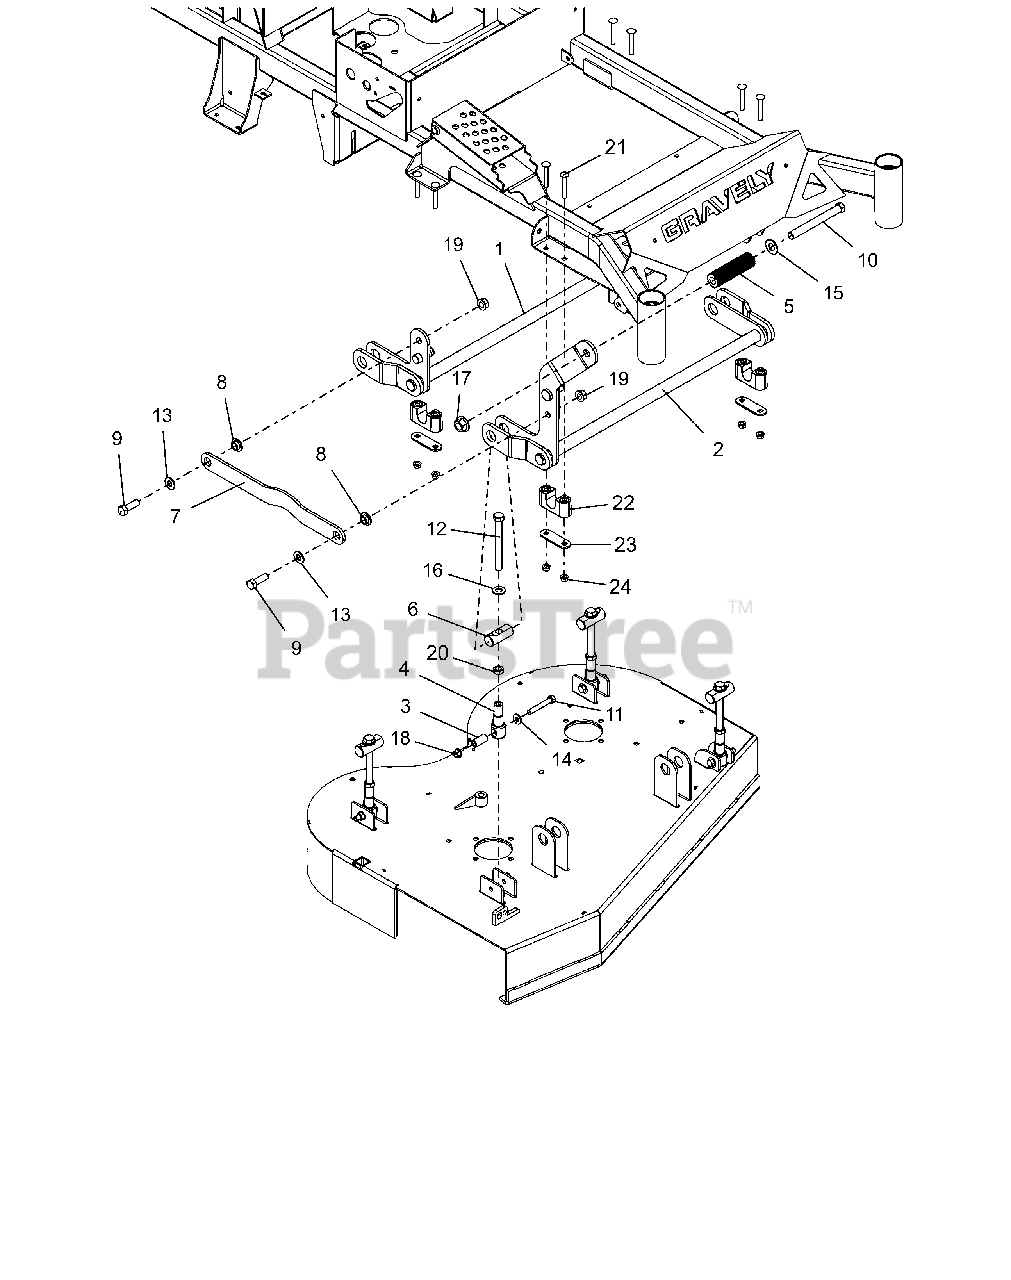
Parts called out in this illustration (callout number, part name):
1	WLDMT, COMPACT REAR DECK LIFT
2	WLDMT, COMPACT FRONT DECK LIFT
3	SPACER, DECK LEVELING
4	LINK, DECK LIFT FORMED
5	ROD, FOOT PEDAL (BLACK)
6	PIN, DECK LIFT
7	LINK, DECK LIFT
8	BSHG, FLG .515X.750X.360X1.12
9	BLT,HEX .50-13X1.50 G5 ZCC
10	BLT, HEX .62-11X5.50 G5 FBP
11	BLT, HEX .38-16X2.50 G5 ZCC
12	BLT, HEX 0.5-13X5S GR5 ZCC
13	WSHR,FLT .531X1.062X.095 ZCC
14	WSHR,FLT .375X.875X.083 ZCC
15	WSHRFLT 5/8SAE CARBHARD FBP
16	WSHR, FLT .557X1.040X.102 ZCC
17	NUT,FLG-TOP LK .625-11 FBP
18	NUT-LK-CTR-FLG .375-16 GF ZCC
19	NUT-LK-CTR-FLG .500-13 GG ZCC
20	NUT-JAM .500-13 G2 ZCC
21	BLT, RHSSN.31-18X2.25 G5 ZCC
22	ASM-BUSHING, DECK LIFT
23	PLATE, BEARING SUPPORT
24	NUT,LK-CTR-FLG .31-18 GF ZCC
